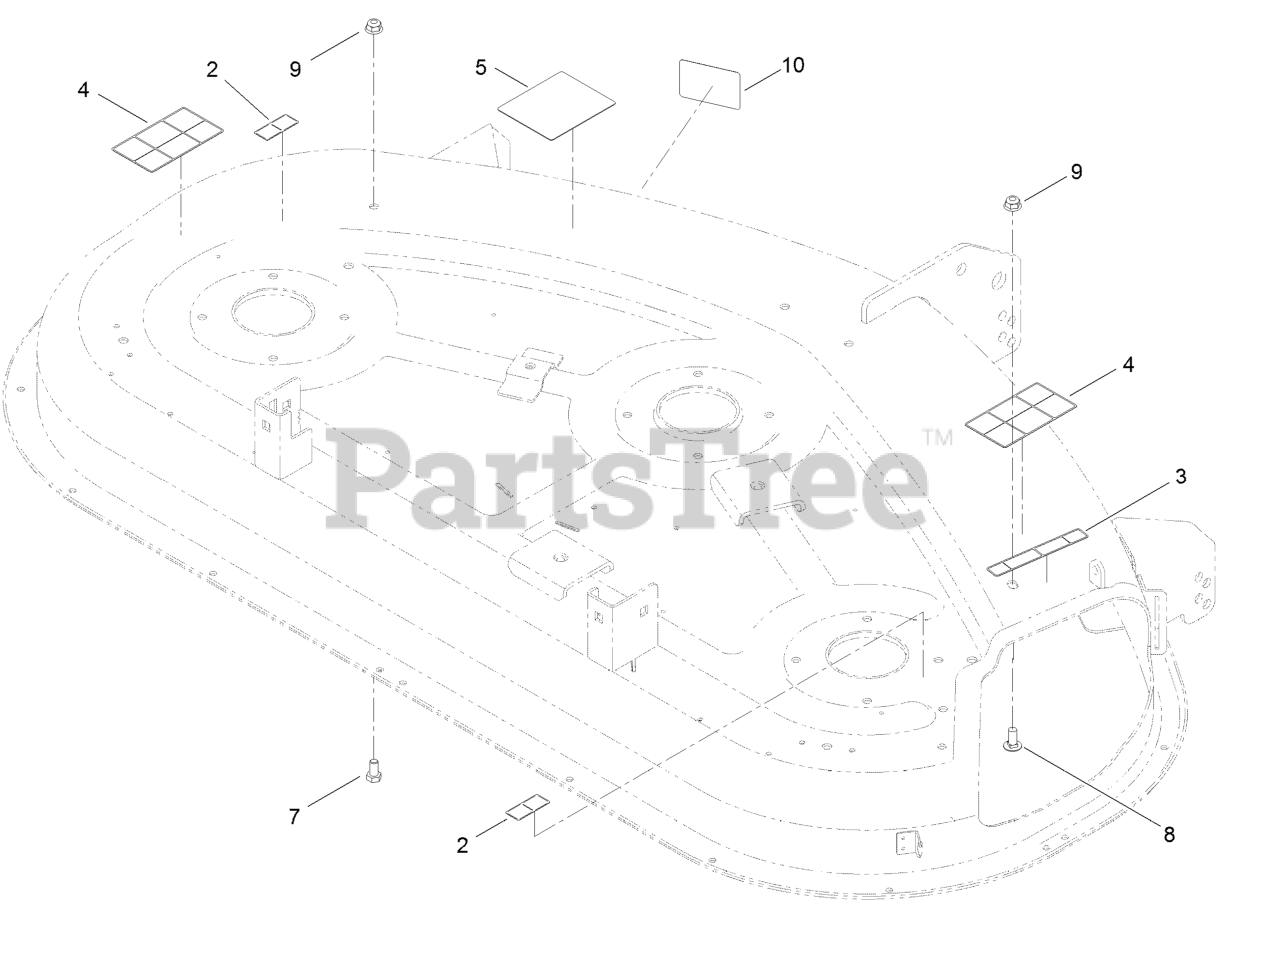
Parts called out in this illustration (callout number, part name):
2	DECAL-DANGER
3	DECAL-DANGER
4	DECAL-DANGER
5	DECAL-ROUTING, BELT
7	SCREW-HH
8	SCREW-CARR
9	NUT-HF, NI
10	DECAL-SCALP, ANTI
